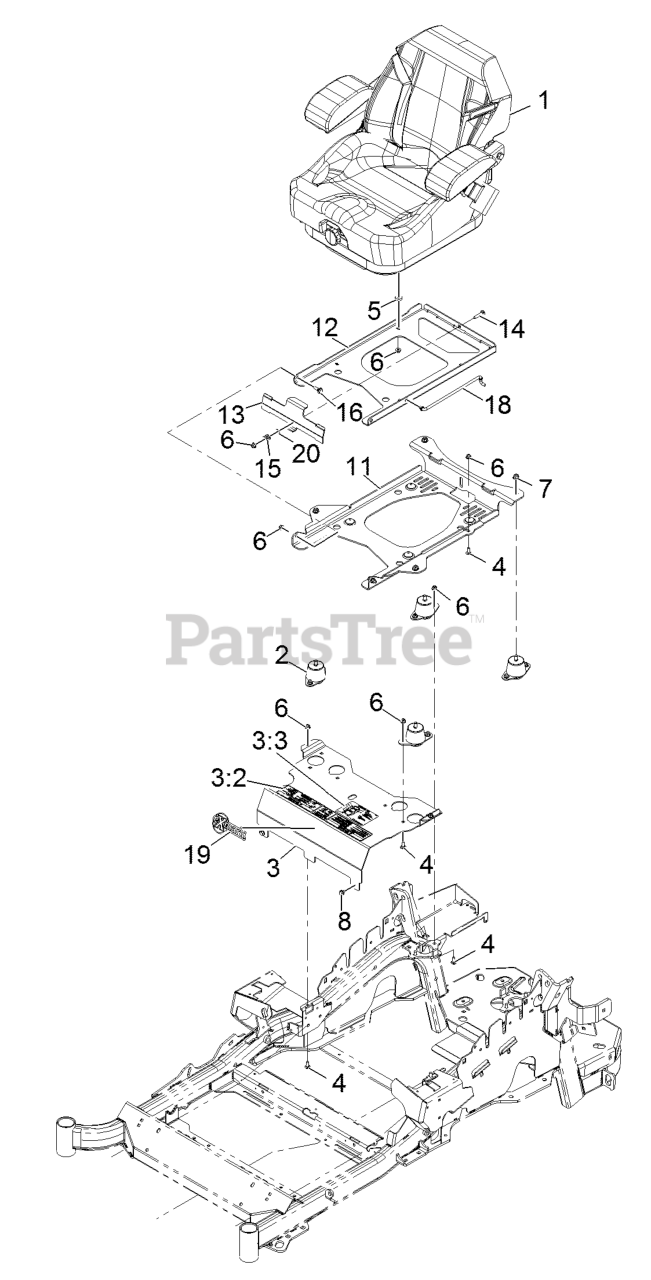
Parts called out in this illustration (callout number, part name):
2	ISOLATOR-SEAT
3	MOUNT-SEAT
3:2	DECAL-CONSOLE
3:3	DECAL-SERVICE AID
4	SCREW-CARR
6	NUT-HF, NI
7	NUT-HF, NI
11	PLATE-TILT, SEAT SUPPORT
12	PLATE-FRAME, SEAT
13	PLATE-LATCH, SEAT
14	BOLT-CARR
15	SPRING-COMPRESSION
16	SCREW-SHOULDER
18	ROD-PROP
20	WASHER-PLAIN
